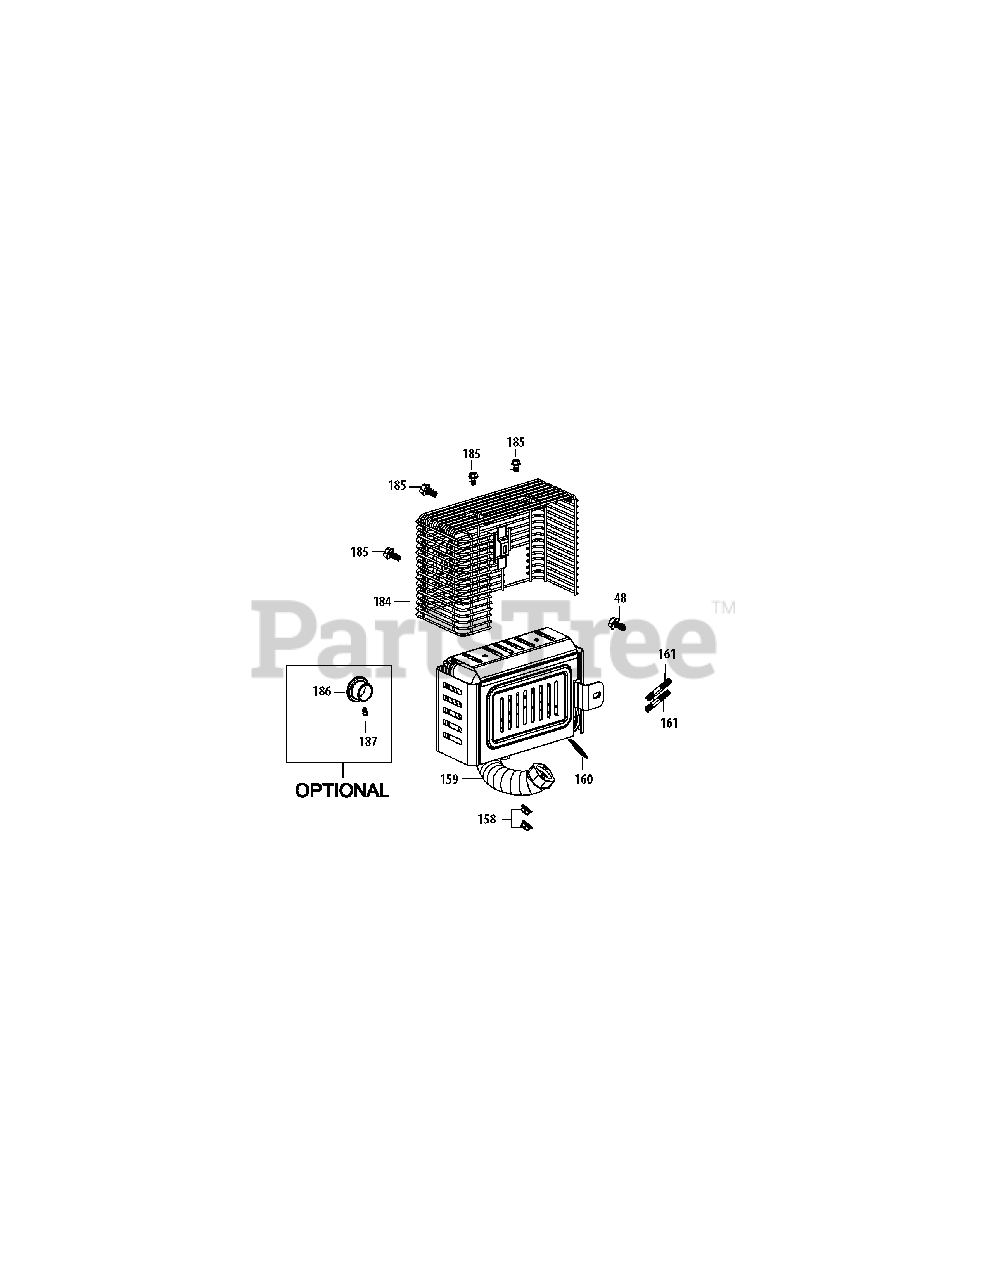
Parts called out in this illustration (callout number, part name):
48	Bolt M6×14
159	Muffler Assembly
160	Exhaust Pipe Muffler Gasket
161	Muff Stud M8×47
161	Muffler Stud Assembly
184	Wire Mesh Muffler Shield
185	Bolt M6×12
186	Spark Arrestor
187	Spark Arrestor Screw
